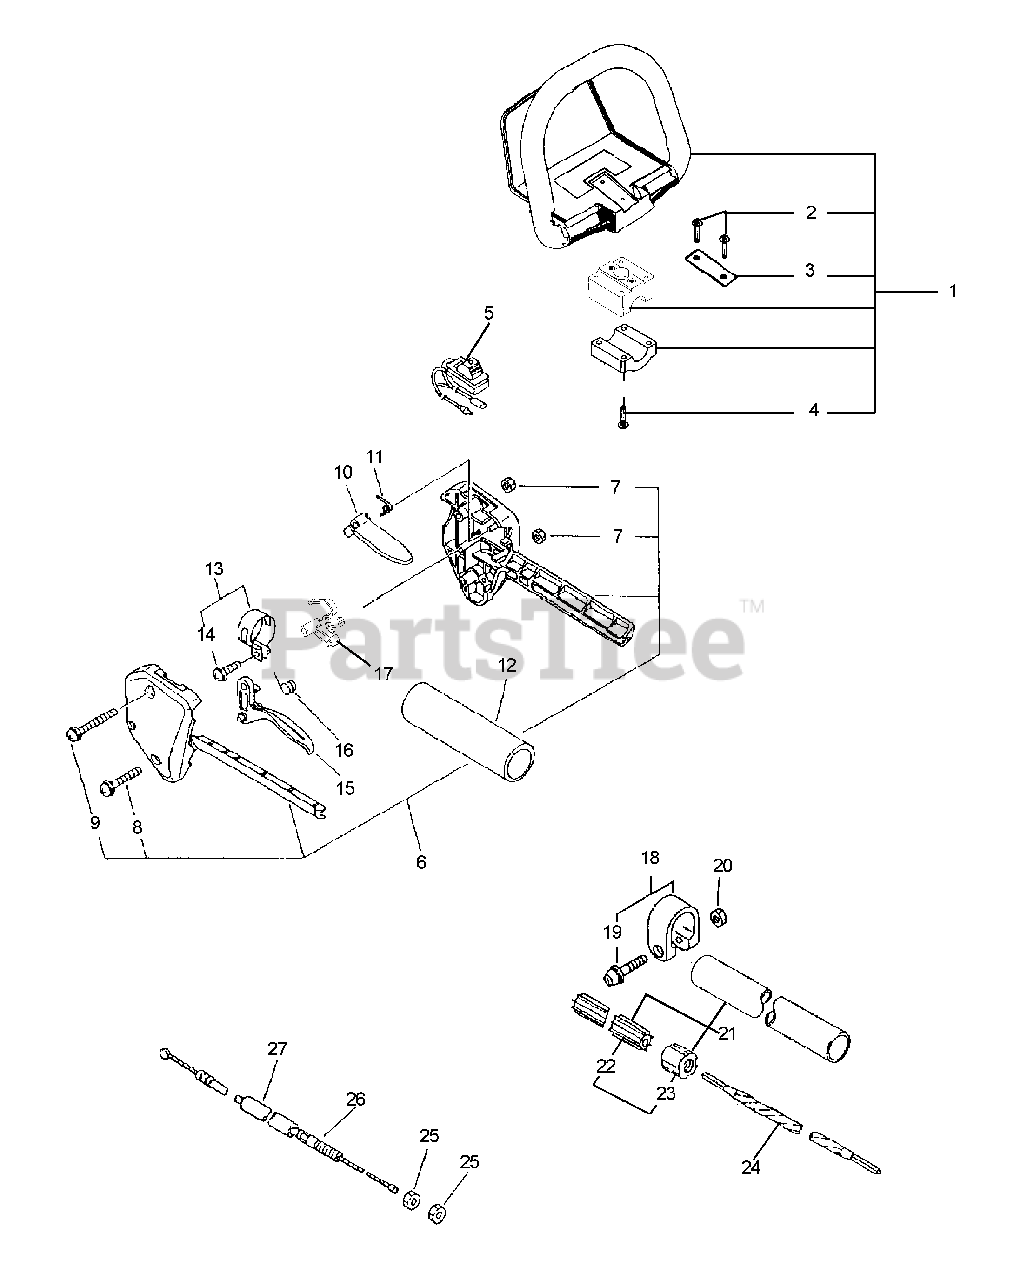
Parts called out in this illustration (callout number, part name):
1	HANDLE ASSY - FRONT
2	SCREW - 5X30
4	SCREW - 5
5	IGNITION SWITCH ASSY
6	THROTTLE BRACKET SET
8	SCREW - 5X25
9	SCREW - 5X35
10	LEVER, TRIGGER LOCKOUT
11	SPRING, LOCKOUT LEVER
12	GRIP, HANDLE - REAR
13	CLAMP KIT
14	SCREW - 5X14
15	TRIGGER, THROTTLE
16	SPRING, TRIGGER
17	LOCKOUT, THROTTLE
18	CLAMP
19	SCREW - 5X28
21	MAIN PIPE ASSY
22	LINER - FLEXIBLE
24	DRIVESHAFT - FLEXIBLE
26	CABLE, THROTTLE
27	TUBE, PROTECTIVE - CORRUGATED
